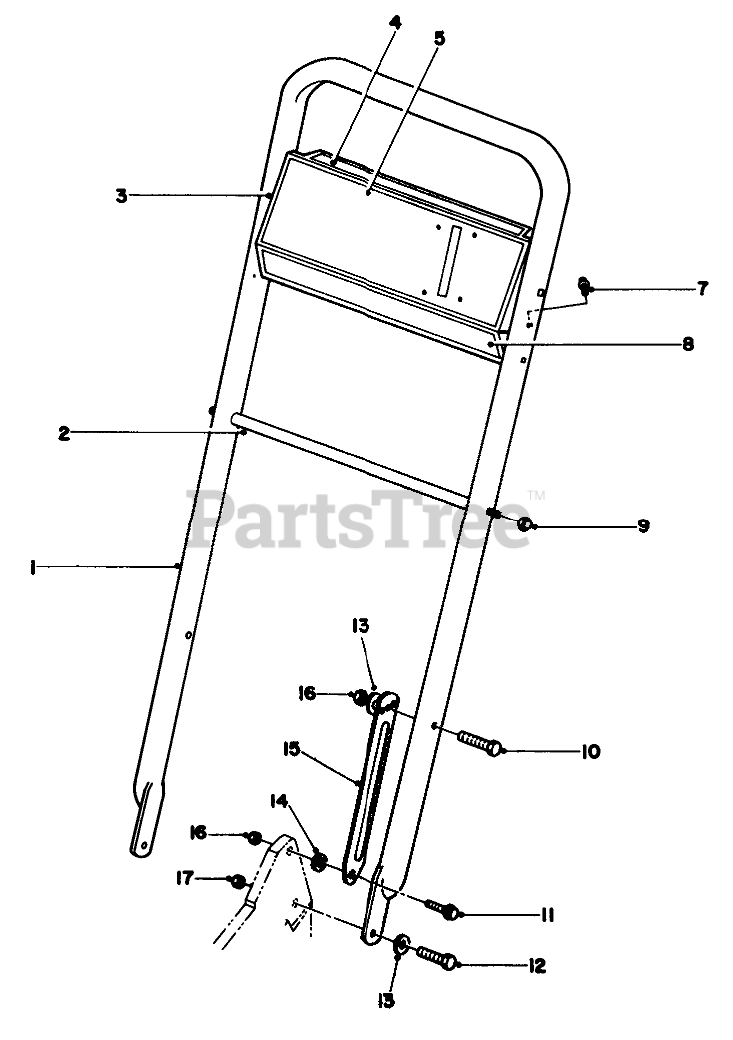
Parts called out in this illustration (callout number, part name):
1	Handle
2	ROD-SUPPORT, BAG
3	Panel-Control (Incl. Ref. #4, 5, & 8)
4	DECAL-PANEL, DANGER
5	DECAL-CONTROL PANEL
6	SCREW-PPH
7	SCREW-HWHTF
8	DECAL-PANEL, PROLINE
9	NUT-CAP
10	SCREW-HH
11	SCREW-SHOULDER
12	SCREW-HH
13	WASHER-BELLEVILLE
14	SPACER
15	Latch-Handle
16	NUT-LOCK, NI
17	NUT-LOCK, NI
